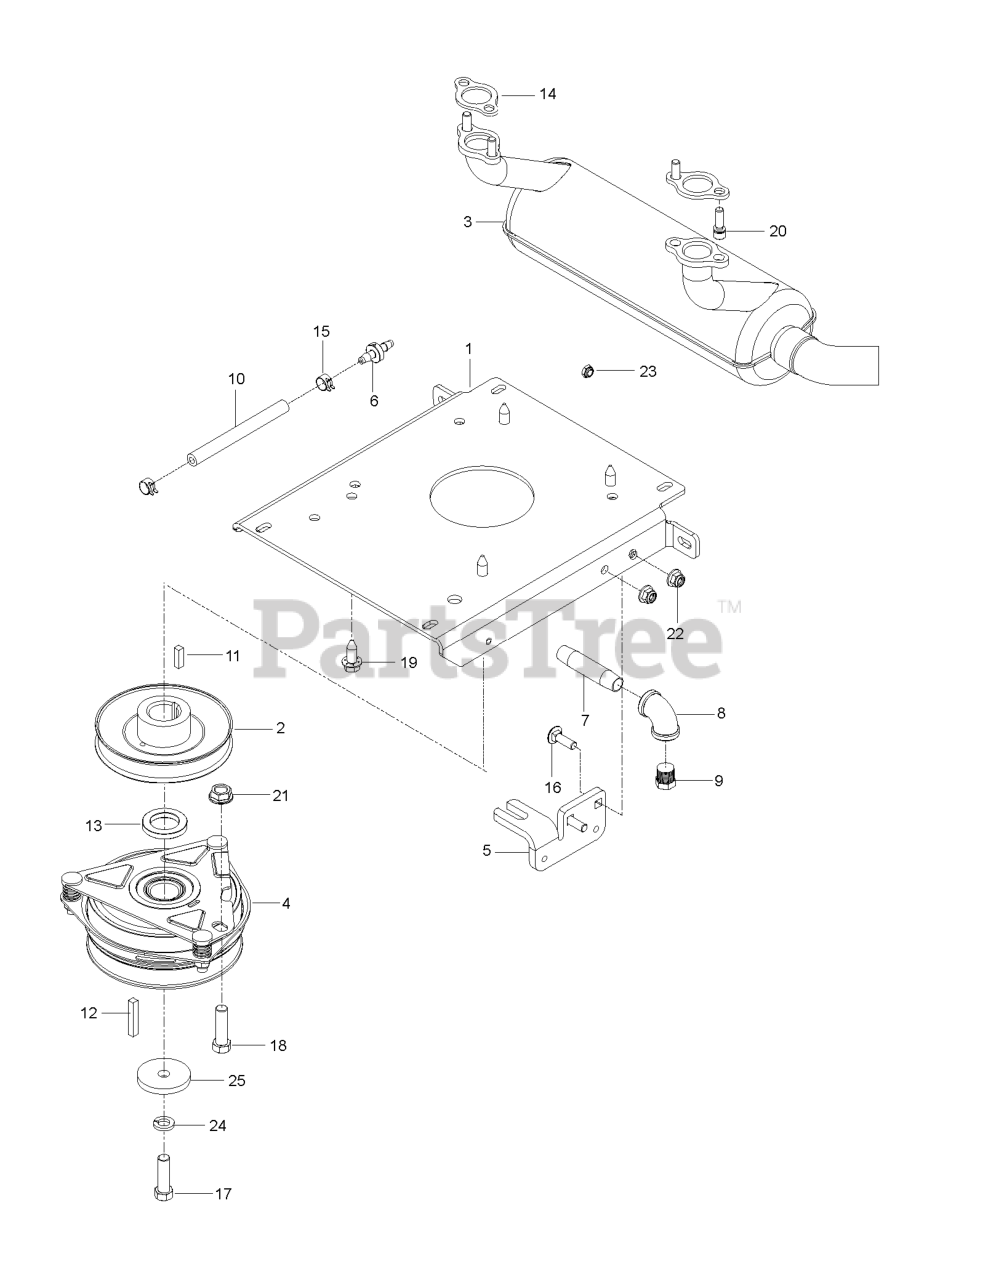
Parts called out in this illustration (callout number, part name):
1	PLATE.ENGINE.BLACK
2	PULLEY, ENGINE
3	MUFFLER, B&S CYCLONIC
4	CLUTCH, 150 FT/LBS
5	STOP, CLUTCH, OGURA
6	VALVE, CHECK, .25
7	PIPE NIPPLE 3/8 X 3
8	90 DEG.ELBOW 3/8NPT
9	PLUG, DRAIN 3/8 NPTF
10	FUEL LINE 5"
11	KEY 1/4 SQ X 1.0
12	KEY 1/4 SQ X 2
13	SPACER, .25 X 1.135 I.D.
14	GASKET.MUFFLER.B&S.REF #273485
15	HOSE CLAMP
16	RHSNB 5/16C X 1
17	CLUTCH BOLT7/16-20X1.5GR5.96HR
18	HCS 7/16-14 X 1-1/4 GR 5 ZD
19	SCREW 3/8-16X1
20	SCREW.SOCKET.HEAD.5/16-18
21	NUT 7/16C WHIZ
22	5/16-18 NYLOC FLANGE NUT
23	JAM NUT 1/4C (2 2 PW01)
24	WASHER 7/16 LOCK
25	BLADE WASHER
